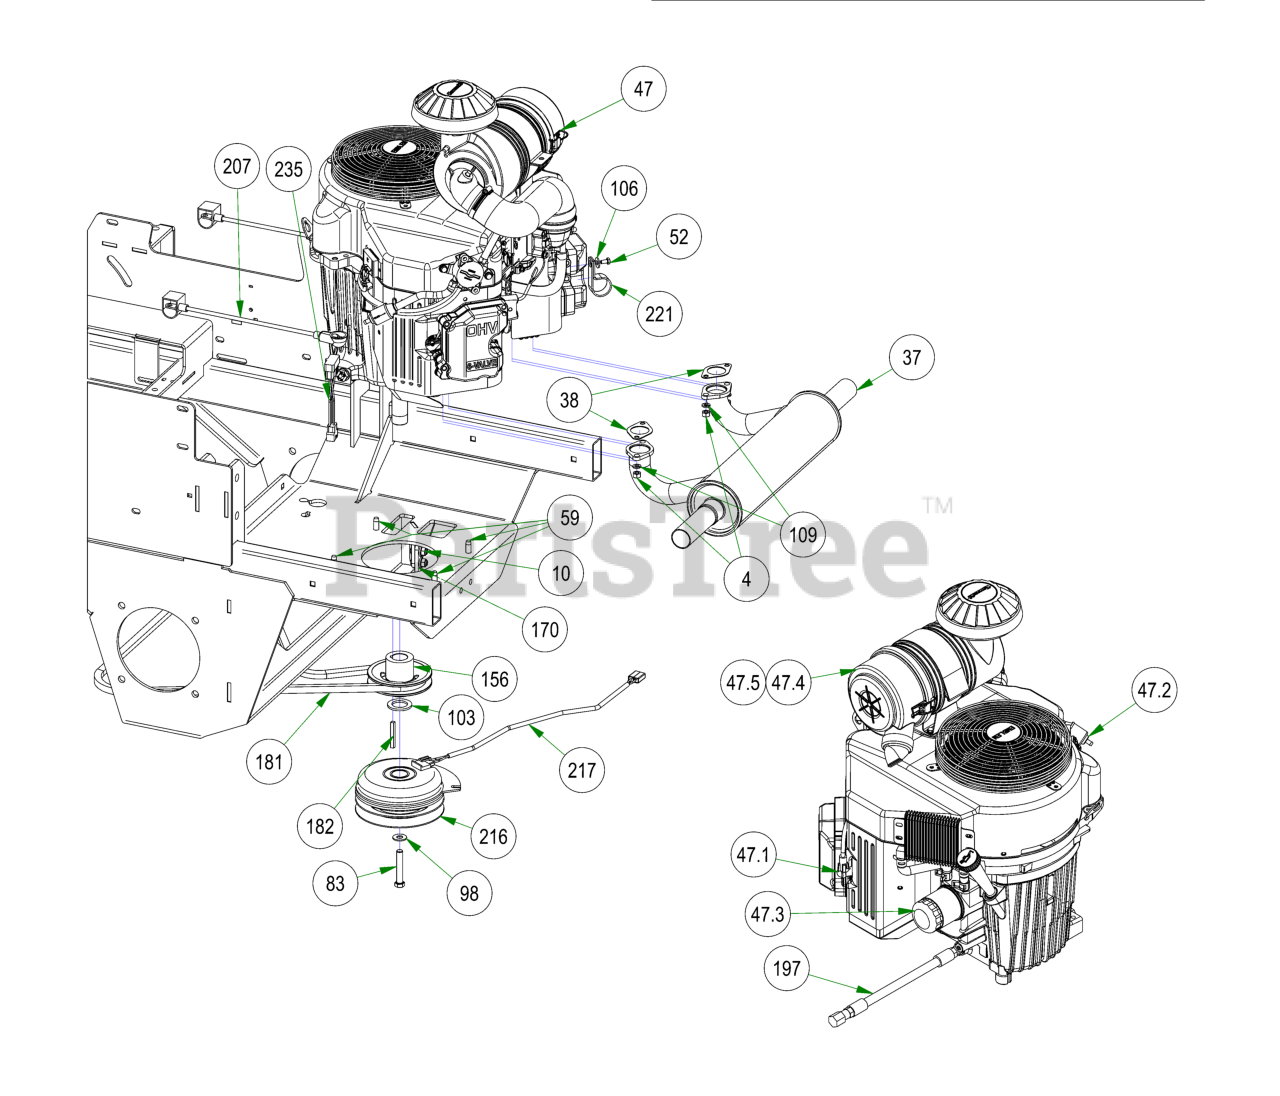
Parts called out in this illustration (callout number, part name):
4	M8-1.25 DIN 934 HEX NUT (CL.8) ZINC
10	3/8-16 NYLON INSERT FLANGE LOCKNUT (GR.F) ZINC
37	2019 Rebel/Rogue Kawasaki 1000 Muffler
38	Exhaust Gasket
47	Kawasaki FX1000 Engine
47.1	Spark Plug - Kawasaki
47.2	Universal Inline Fuel Filter
47.3	Oil Filter
47.4	Canister Air Filter- Outer
47.5	Canister Air Filter- Inner
47.6	Exhaust Gasket
52	M6-1.0 X 12MM DIN 933 HEX TAP BOLT (CL 8.8) ZINC
59	3/8-16 X 1-1/8HEX WASHER UNSLOT SERRATED
81	3/8-16 X 1 CARRIAGE BOLT (GR.5) ZINC
83	7/16-20 X 2-1/2 HEX Bolt GR 8 W/ Patch
98	3/8 FLAT WASHER USS (1" OD) ZINC
103	1.140 ID X 1.750 OD X .132 THICK FLAT WASHER PLAIN
106	1/4 USS FLAT WASHER (3/4 OD) ZINC
109	5/16 SPLIT LOCKWASHER ZINC
156	4 3/4 Motor Pulley
170	Rebel Clutch Tab
181	2019 Rebel Pump Belt
182	1/4 X 2 SQ MACHINERY KEY 1018 STL PLAIN
197	Kawasaki Oil Drain
207	14" Red Battery Cable-Base Outlaw
216	Clutch Assembly
217	Clutch Pigtail
218	2022 Rebel Frame
221	Diesel Hydraulic Hose Clamp
232	Starter Cable
235	2019 Harness Adaptor-Gen2 FX-ALL
